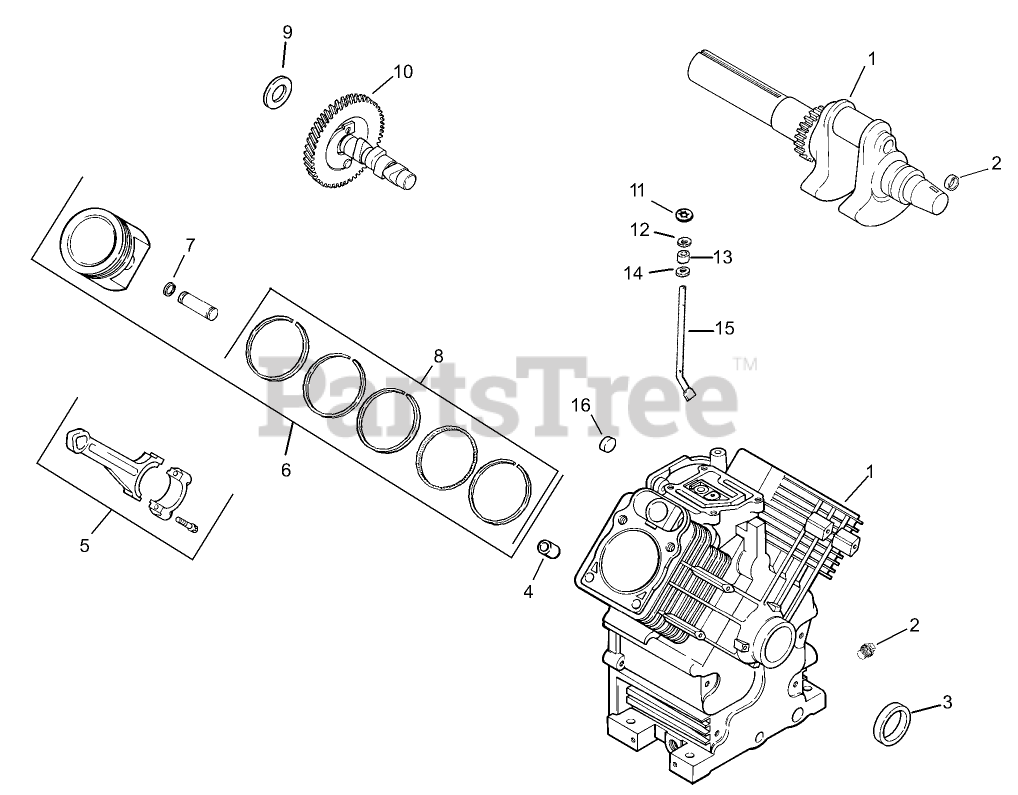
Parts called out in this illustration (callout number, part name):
2	PLUG-PIPE, SQ HD (3/8)
3	SEAL-OIL
4	Pin-Locating
5	Rod-Connecting (Standard)
5	Rod-Connecting (.25)
6	Set-Piston w/ Ring (STD)(Incl. Ref.#7&8)
6	Piston ASM (.08)
6	Piston ASM (.25)
6	Piston ASM (.50)
7	RETAINER-PIN, PISTON
8	RING SET (STD AND .08)
8	Ring Set (.25)
8	Ring Set (.50)
9	SHIM-CAMSHAFT (RED .032)
9	SHIM-CAMSHAFT (BLACK .04)
9	SHIM-CAMSHAFT (WHITE .028)
9	SHIM-CAMSHAFT (BLUE .03)
9	SHIM-CAMSHAFT (YELLOW .034)
9	SHIM-CAMSHAFT (GREEN .036)
9	SHIM-CAMSHAFT (GRAY .038)
10	Camshaft Kit
11	RETAINER-RING
12	WASHER-FLAT (9MM)
13	SEAL-CROSS SHAFT, GOVERNOR
14	WASHER-FLAT (11/32)
15	Shaft-Cross, Governor
16	PLUG-CUP
